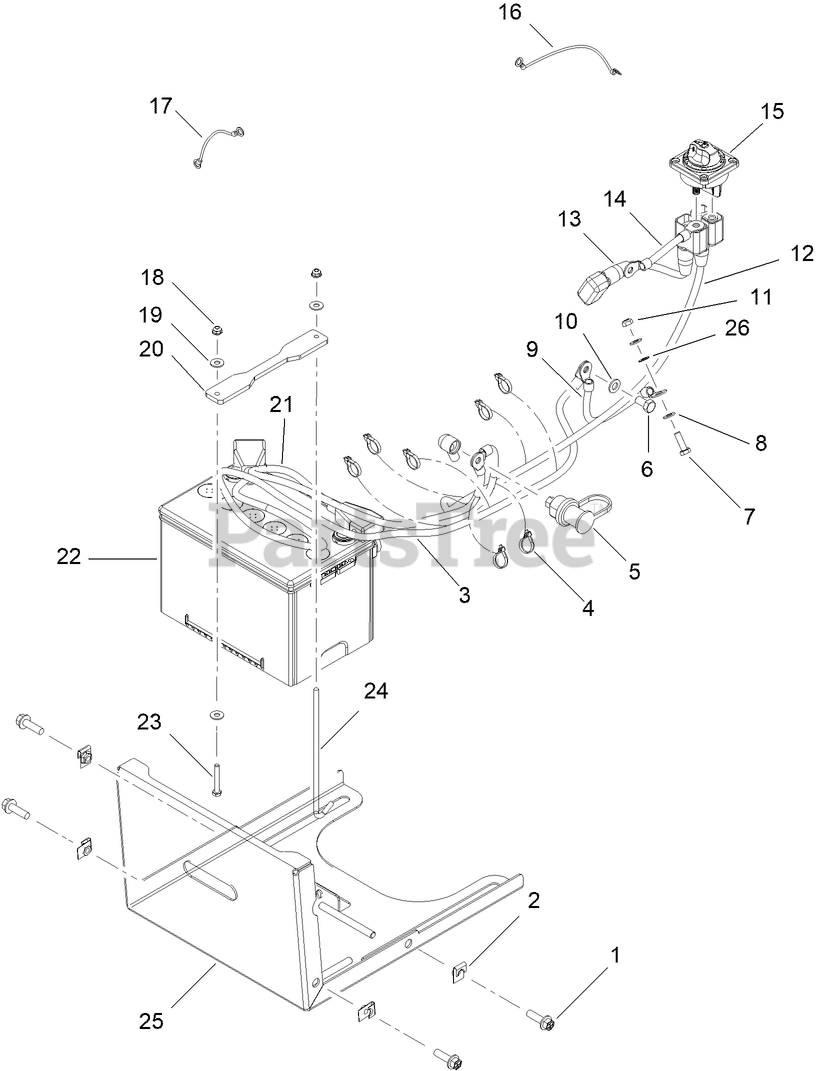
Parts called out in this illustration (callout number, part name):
1	SCREW-HHF
2	NUT-SPRING
3	BATT CABLE NEG. (1GA X 46 INCHES, BLK)
4	CABLE TIE (1/16" TO 4")
5	BATTERY JUMPER TERMINAL (RED)
6	SCREW-HH
7	SCREW-HH
8	WASHER-PLAIN
9	GROUND STRAP
10	WASHER-FLAT
11	NUT-HEX
12	JUMP START CABLE (1GA X 38 INCHES, RED)
13	STARTER CABLE (1GA X 8 INCHES, RED)
14	TRIFUSE CABLE (1GA X 4.25 INCHES, RED)
15	SQUARE DISCONNECT SWITCH (300A)
16	GROUND BRAID - L ARM PANEL TO CRUISE
17	GROUND BRAID - L ARM PANEL TO CRUISE
18	NUT-HF
19	WASHER-FLAT
20	BATTERY HOLD DOWN
21	BATT CABLE POS. (1GA X 30 INCHES, RED)
22	BATTERY-775CCA, 12V AGM
23	SCREW-HH
24	J-HOOK
25	BATTERY TRAY - WELD
26	WASHER-LOCK
